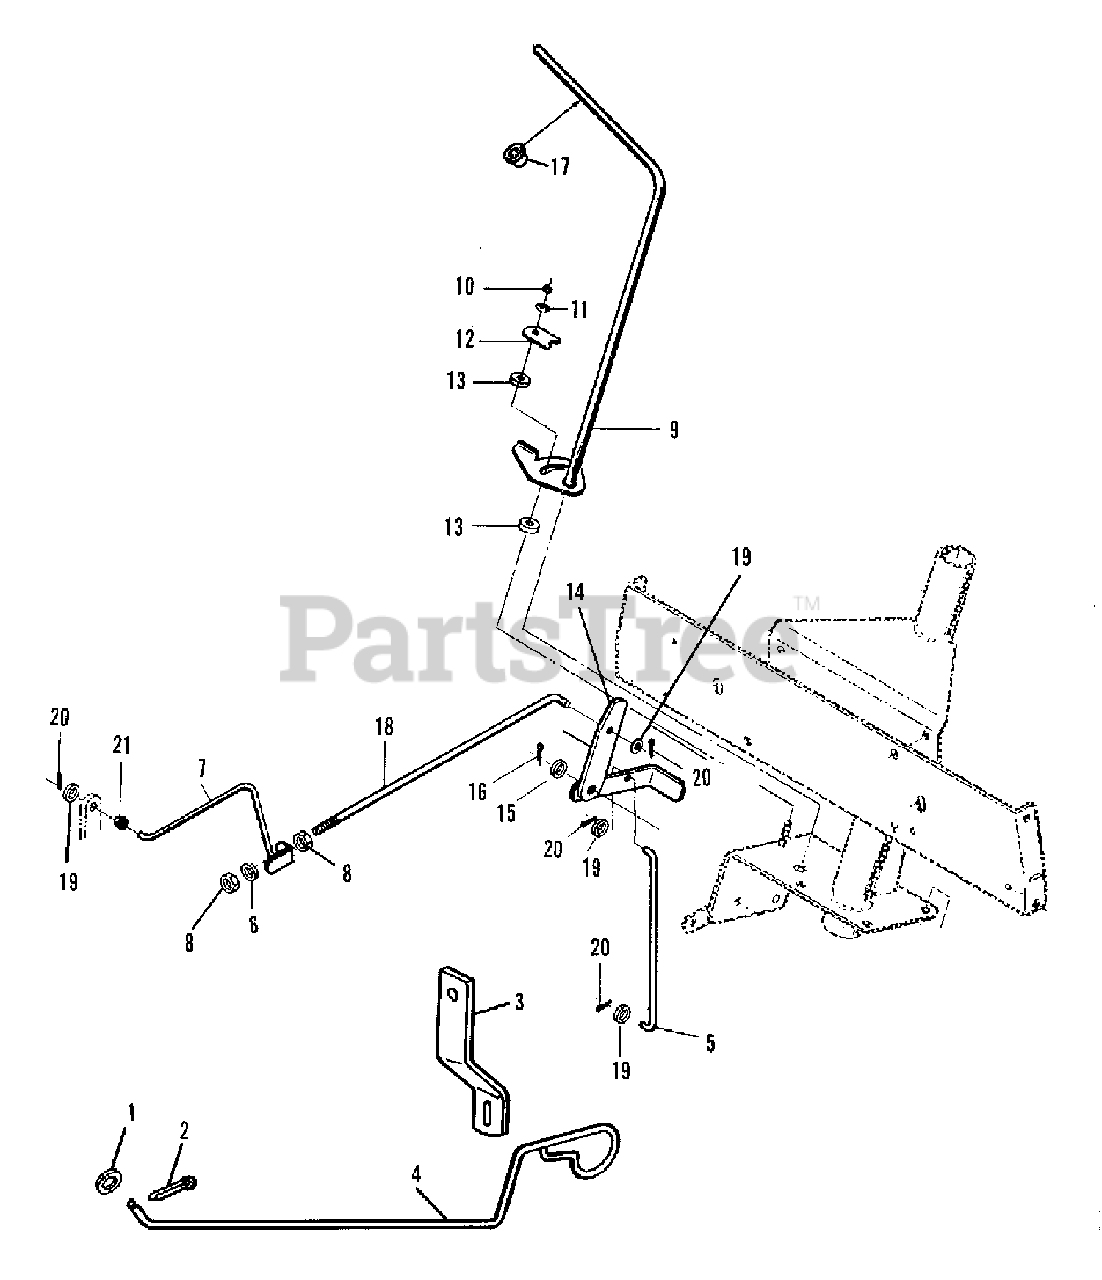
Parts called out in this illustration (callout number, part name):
2	PIN, cotter
3	BRACKET, rod
4	ROD, stopper
6	LOCKWASHER, M6
9	LEVER, throttle
13	GASKET, friction
14	ARM, stopper
16	PIN, cotter
17	BUSHING, lever
20	PIN, cotter
